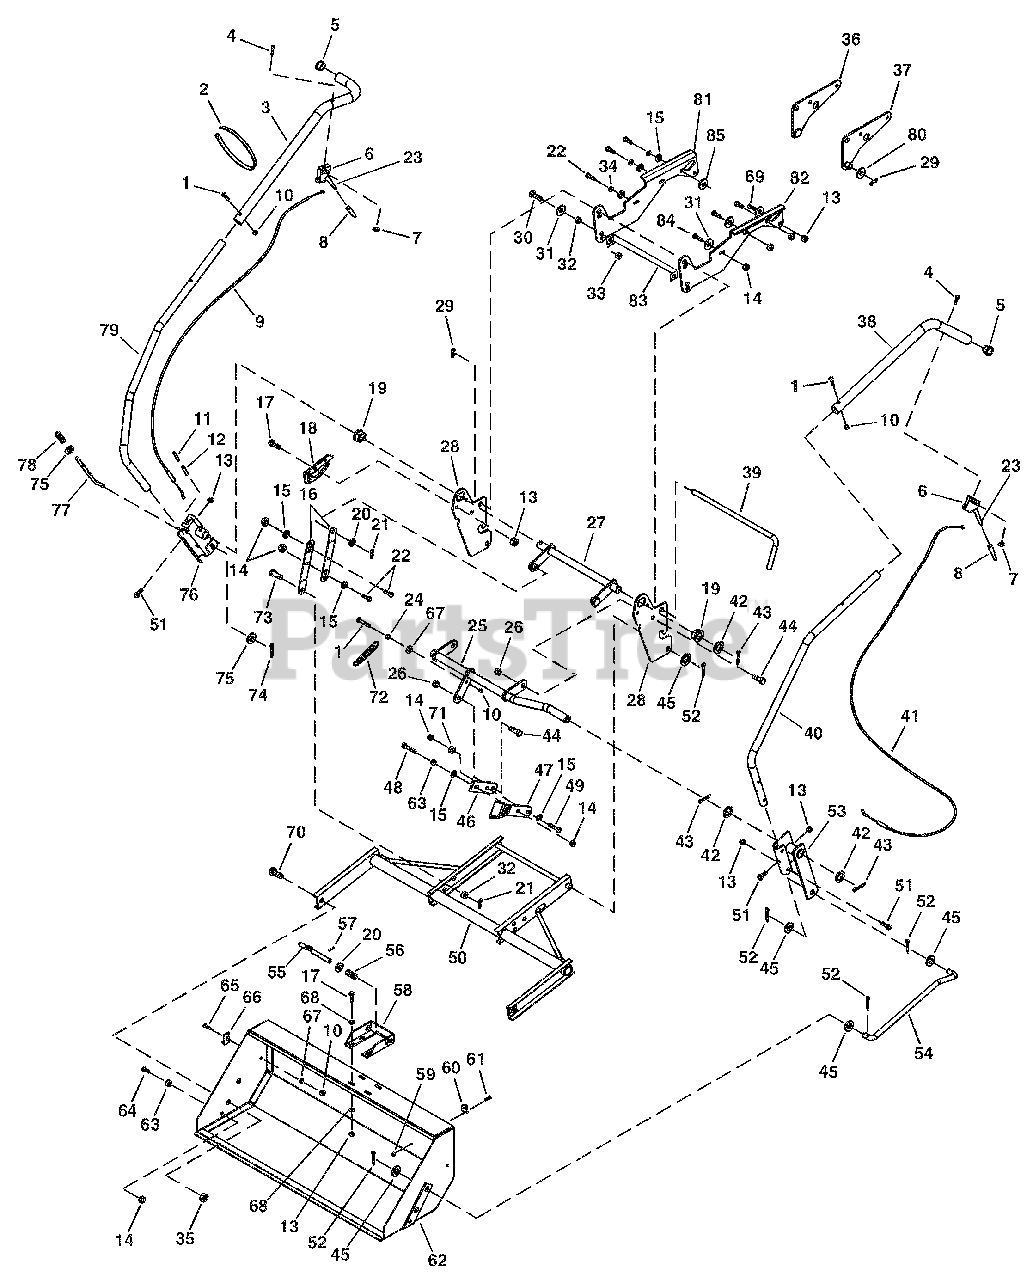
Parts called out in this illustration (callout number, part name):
1	Hex Bolt, 1/4-20 x 1-3/4"
2	Cable Tie
3	Lift Handle Extension
4	Oval Screw, 10-24 x 1-1/2"
5	Plastic Plug, 1-1/4" O.D. Tube
6	Trigger Housing Assembly
7	Square Nut, #10-24
8	Grip, Black
9	Cable, Lift
10	Nylock Nut, 1/4"
11	Roll Pin, 3/16" x 1-3/4"
12	Roll Pin, 5/16" x 1-3/4"
13	Nylock Nut, 5/16-18
14	Nylock Nut, 3/8-16
15	Flat Washer, 3/8"
16	Lift Strap
17	Hex Bolt, 5/16-18x1"
18	Lift Bracket
19	Flange Bearing with Flats
20	Flat Washer, 1/2" x 1"
21	Hairpin Cotter, 3/32" x 1.8"
22	Hex Bolt, 3/8-16x1"
23	Trigger Assembly
24	Hex Nut, 1/4-20
25	Tilt Anchor Assembly
26	Nylock Jam Nut, 1/2-13
27	Lift Arm Assembly
28	Mounting Bracket
29	Hairpin Cotter, 3/32" x 2-5/16"
30	Hex Bolt 1/2-13 x 1-3/4"
31	Flat Washer, 1/2" x 1-1/2"
32	Spacer, 0.52" x 0.75" x 0.5"
33	Nylock Nut, 1/2-13
34	Lock Washer, 3/8"
35	Nylock Nut, 5/8-11
36	Right (Short) Side Plate
37	Left (Short) Side Plate
38	Dump Handle Tube Extension
39	Attachment Rod
40	Dump Handle Tube
41	Dump Control Cable
42	Washer, 1.59" x 1.032" x 0.60"
43	Cotter Pin, 1/8" x 1-1/2"
44	Hex Bolt, 1/2-13 x 1"
45	Flat Washer, 5/8" x 1-1/4" x 16 Ga.
46	Tilt Bracket Extension Strap
47	Tilt Bracket
48	Hex Bolt, 3/8-16 x 2"
49	Hex Bolt, 3/8-16 x 1 -3/4"
50	Lift Frame Assembly
51	Hex Bolt, 5/16-18x1 -3/4"
52	Cotter Pin, 1/8" x 1-1/4"
53	Dump Pivot Bracket
54	Dump Control Rod
55	Dump Control Pin
56	Compression Spring
57	Spring Pin, 1/8" x 1"
58	Pin Stop Bracket
59	Nylock Nut, #10-32
60	Hose Clamp
61	Truss-Head Bolt #10-32 x 5/8"
62	Bucket Assembly
63	Hex Nut, 3/8-16
64	Hex Bolt, 3/8-16 x 1-1/4"
65	Carriage Bolt, 1/4-20x3/4"
66	Tilt Stop Bracket
67	Flat Washer, 1/4"
68	Flat Washer, 5/16"
69	Carriage Bolt, 5/16" x 1"
70	Hex Bolt, 5/8-11 x 1-1/2"
71	Spacer, 3/8" I.D. x 7/8" O.D. x 3/8"
72	Extension Spring
73	Clevis Pin, 1/2" x 1"
74	Cotter Pin, 1/8" x3/4"
75	Flat Washer, 3/8" x 13/16" x 1/16"
76	Index Bracket Assembly
77	Index Rod
78	Spring, Compression
79	Lift Handle Tube
80	Flat Washer, 3/4"
81	Right (Long) Side Plate
82	Left (Long) Side Plate
83	Frame Brace
84	Bolt, Carriage 3/8-16x1"
85	Washer, .375" x 1.26" x .172"
